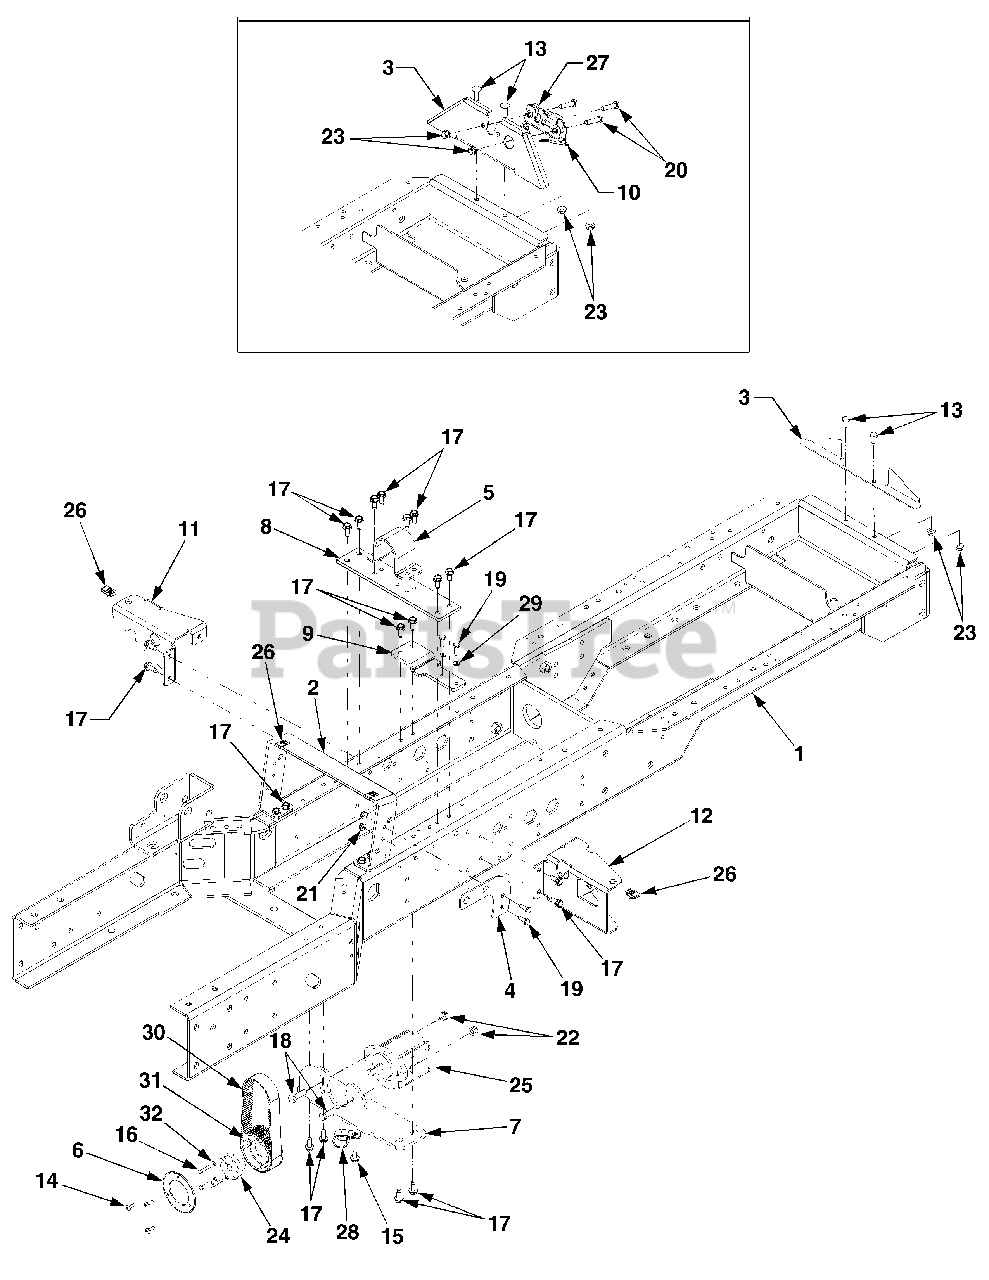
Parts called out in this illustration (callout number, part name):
2	Bracket, Front Seat Mount
4	Bracket, Fitting Mtg.
5	Shield, Drive Shaft
6	Keeper, Belt
7	Bracket, Aux. Pump Mtg.
8	Shield Lower Drive Shaft
9	Plate, Filter Mounting
10	Lever, Hood Latch — Mfg. Code 1C315G and before
11	Bracket, Running Board Mtg.
12	Bracket, Running Board Mtg.
13	Screw, Carriage, 5/16-18 x 1.0 - Code 1C315G and before
13	Screw, Hex Cap, 5/16-18 x .625 GR5 - Mfg. Code 1D015G and after
14	Screw, Truss Hd. Mach. #10-24 x .5
15	Screw, Hex Wash. Hd Tapp 5/16-18 x .5
16	Screw, Hex Mach. #10-24 x .5
17	Screw, Hex Wash. Hd. Tapp, 5/16-18 x .75
18	Screw, Hex Cap, 3/8-16 x 1.25 GR5
19	Screw, Hex Cap, 1/4-20 x .75 GR5
20	Screw, Hex Cap, 5/16-18 x 1.375 GR5 - Mfg. Code 1C315G and before
21	Nut, Hex Nylon Flange Lock, 1/4-20 GRF
22	Nut, Hex Lock, 3/8-20 GrB
23	Nut, Hex Flange Insert Lock, 5/16- 16 GrF (Replaces 712-3004A)
24	Bushing, Tapered
25	Pump, Aux. Hydraulic
26	Nut, U Speed, 5/16-18
27	Latch, Hood — Mfg. Code 1C315G and before
29	Washer,Lock, 1/4
30	Belt, HTS, 5 x 25 x 500
31	Pulley, 52T Cog
32	Washer, Lock, #10
